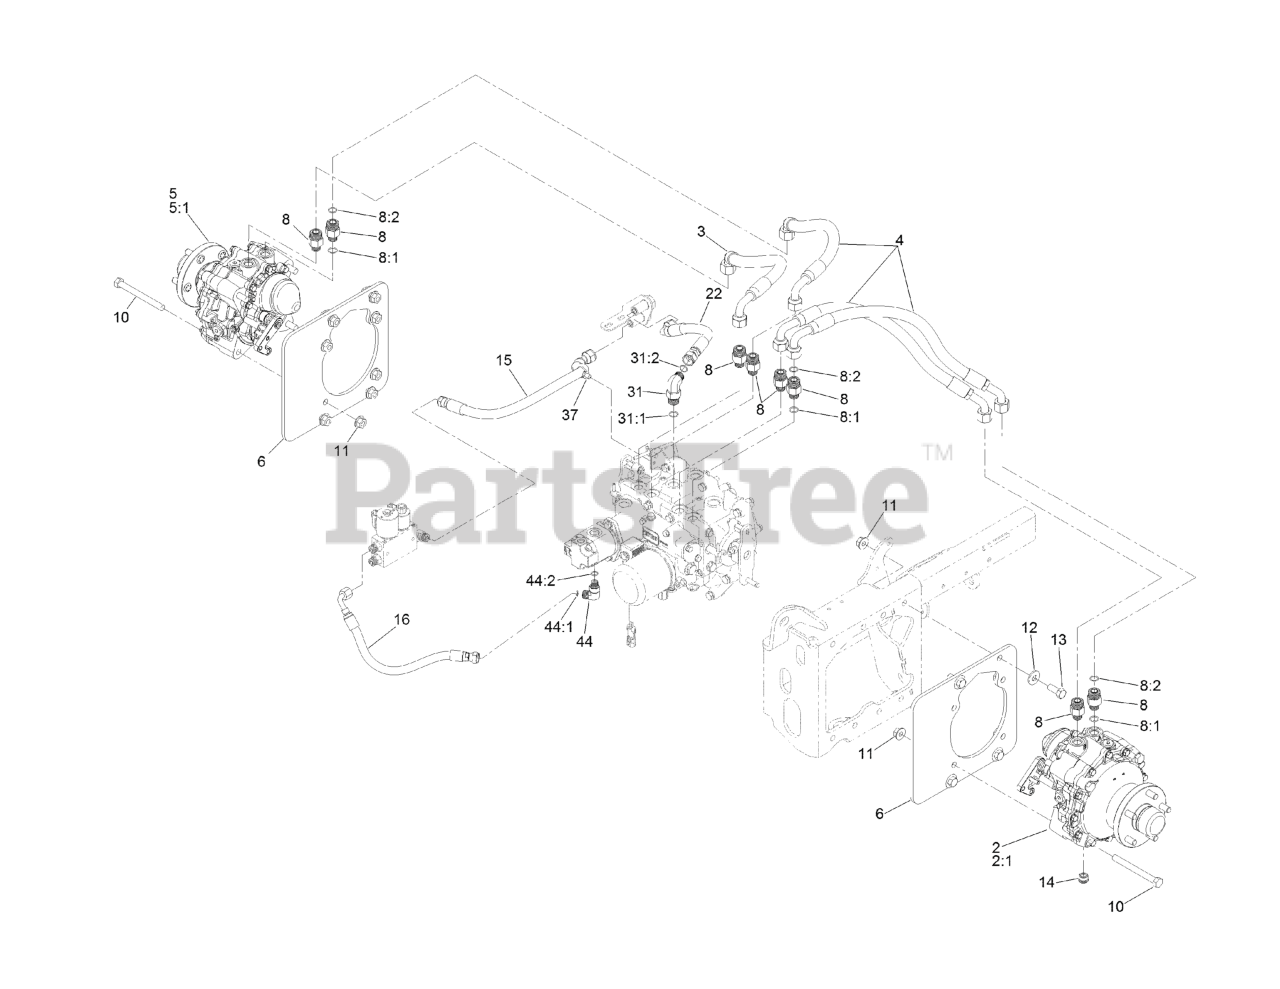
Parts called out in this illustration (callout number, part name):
2	MOTOR-HYD, LH
2:1	5 STUD WHEEL HUB KIT
3	HOSE ASM
4	HOSE ASM
5	MOTOR-HYD, RH
5:1	5 STUD WHEEL HUB KIT
6	PLATE-MOTOR
8	FITTING-STRAIGHT
8:1	O-RING
10	SCREW-HH
11	NUT-HHF
12	WASHER-SPRING
13	SCREW-HH
14	PLUG-MAGNETIC
15	HOSE ASM
16	HOSE ASM
22	HOSE ASM
31	FITTING-ELBOW, 90 DEG
31:1	O-RING
31:2	O-RING
37	CLIP-TIE
44	FITTING-ELBOW, 90 DEG
44:1	O-RING
44:2	O-RING
